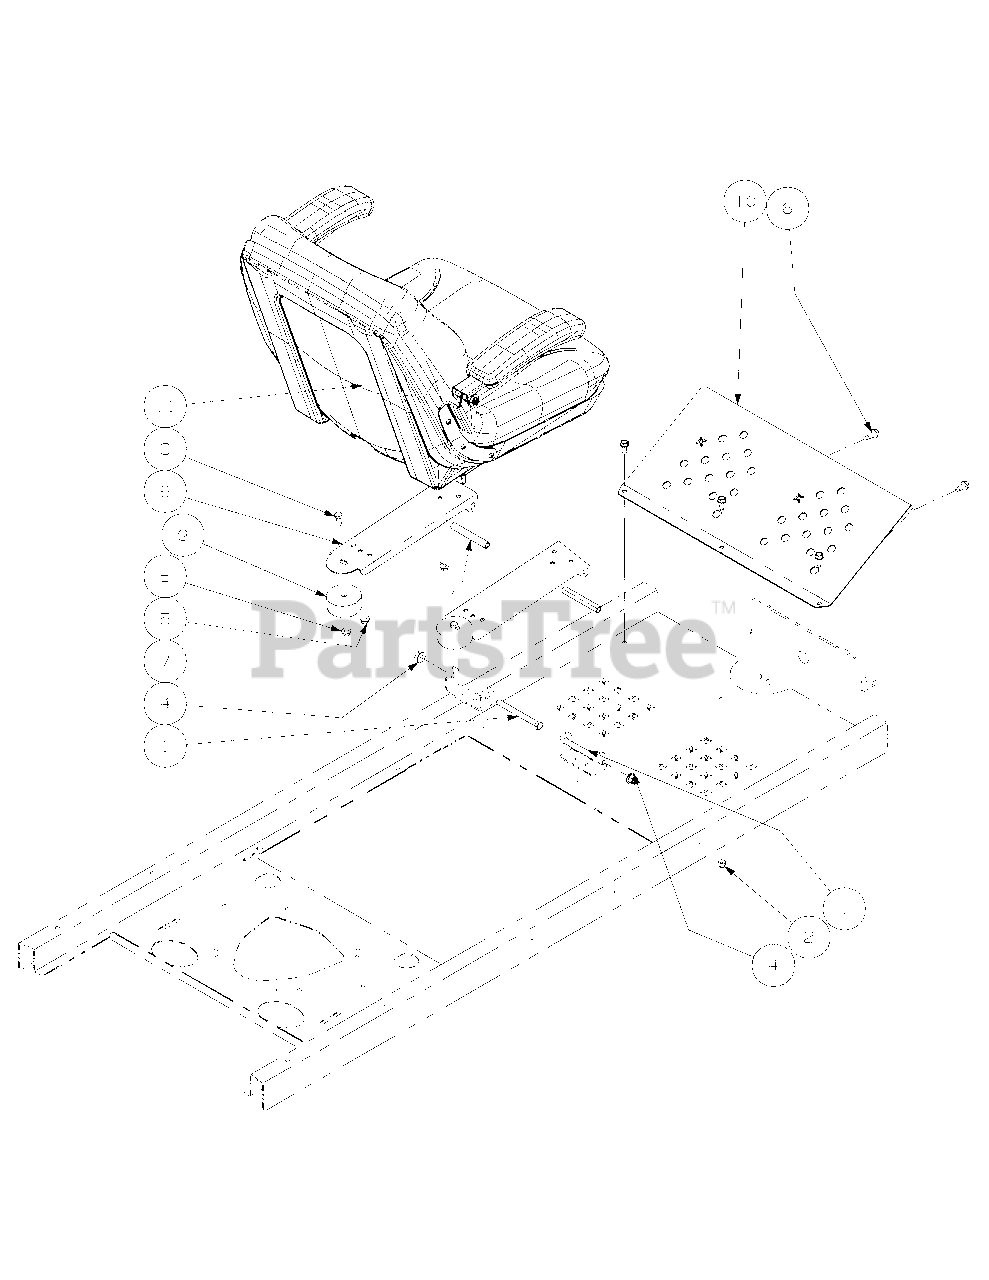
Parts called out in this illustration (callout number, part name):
1	Hex Cap Screw, 3/8-16, 4.00
2	Nylock Nut, 5/16-18
3	Hex Cap Screw, 5/16-18 x .75
4	Flange Lock Hex Nut, 3/8-16
5	Nut, 5/16-18, Hex Flange Lock
6	Self Tapping Screw 5/16-18 x .750
7	Spacer, .370 ID x .500 OD x 3.45
8	Seat Mounting Bracket
9	Bumper, 2.50 OD x 1.13 Long
10	Foot Rest Bracket
11	Seat
